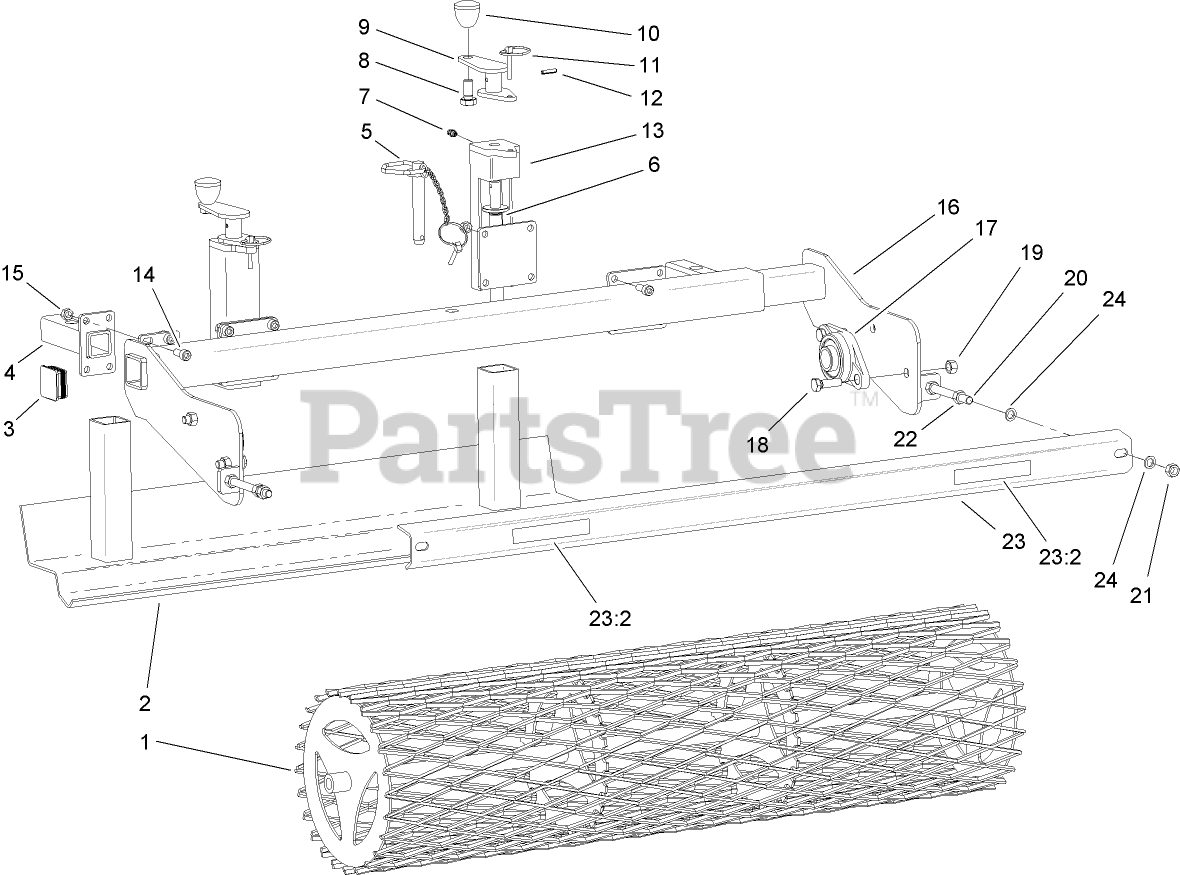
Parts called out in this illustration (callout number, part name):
1	ROLLER-MESH
2	BLADE-GRADER
4	ARM-MALE
5	PIN-DRIFT
7	ZERK-GREASE
8	SCREW-HH
10	HANDLE
11	PIN-LOCKING
13	TUBE-HANDLE, FEMALE
14	SCREW-HSH
15	NUT-LOCK, NI
16	ROLLER FRAME ASM
17	BEARING ASM
18	BOLT-HH
19	NUT-HEX
20	BOLT-HH
21	NUT-LOCK
23	SCRAPER PLATE ASM
23:2	DECAL-WARNING
24	WASHER-FLAT
